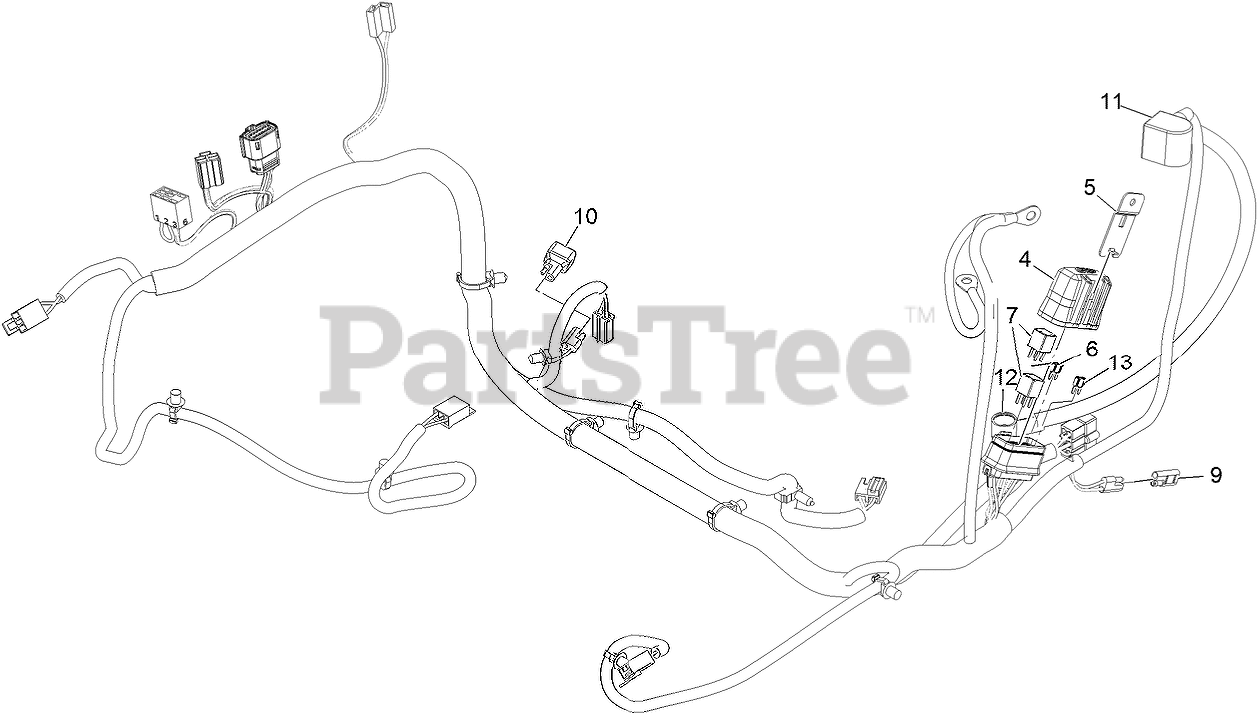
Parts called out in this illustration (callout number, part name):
4	COVER-BLOCK, FUSE
5	CLIP-MOUNTING
6	FUSE-MINI BLADE, 20 AMP
7	RELAY-MICRO
9	CAP-PLUG
11	INSULATOR-BATTERY
12	INSULATOR-SOLENOID
13	FUSE-MINI BLADE, 15 AMP
